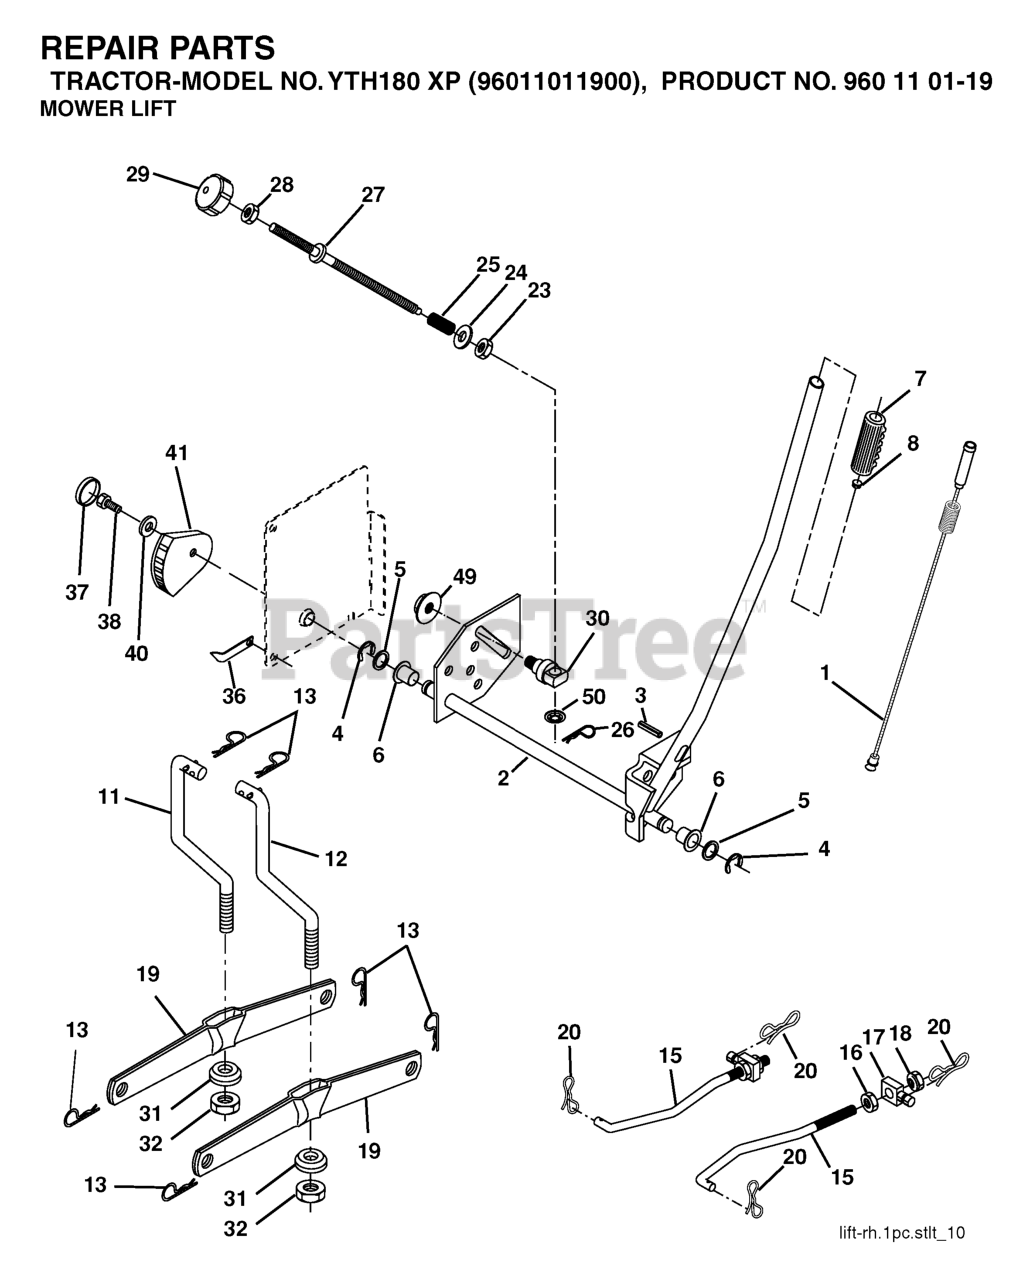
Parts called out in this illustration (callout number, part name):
1	WIRE ASM INNER W/ PLUNGER LT
2	SHAFT ASM R HANDLE
3	PIN GROOVE.
4	RETAINING RING LT
6	BEARING.NYLON
7	GRIP HANDLE
8	PLUNGER BUT KIT
11	LINK LIFT LH
12	LINK LIFT RH
13	RETAINER-SPRNG RB
15	LINK.SUSPENSION.FRONT
16	NUT.HEX.JAM.1/2-13
18	NUT.LK.W/WSH.1/2.
19	ARM.REAR.SUSPENSION
20	PIN.COTTER.7/16.BOW TI.
25	SPRING**
26	RETAINER CLIP
27	ROD ADJ LIFT
28	NUT
29	KNOB INF 3/8-16
31	BEARING.PIVOT.LIFT
32	NUT CROWNLOCK 3/8-24
36	POINTER, HEIGHT INDICATOR(2 2)
38	SCREW 5/16-18X1
41	IND. HEIGHT STLT
49	NUT
50	NUT PUSH M
